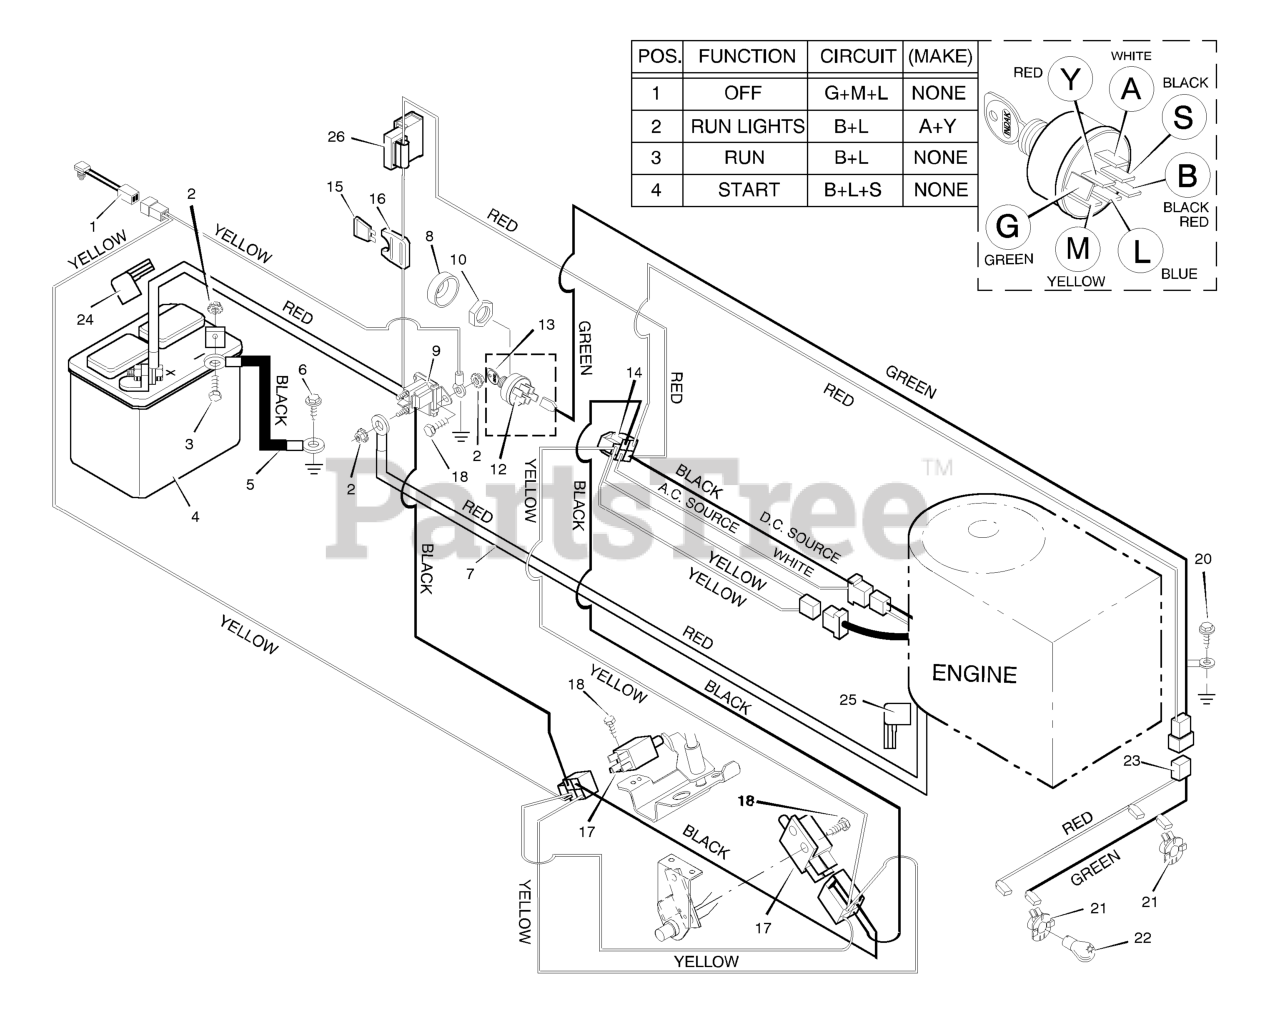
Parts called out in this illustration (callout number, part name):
1	Switch, Seat Sensor
2	Locknut
3	Bolt, Hex
4	Battery
5	Cable, Battery Ground
7	Cable, Red Battery
8	Cap, Ignition
9	Solenoid
10	Nut
12	Switch, Ignition
13	Key, Ignition
14	Harness, Chassis Wire
16	Holder, Fuse
17	Switch, Clutch
20	Screw
21	Socket, Light
22	Bulb, Light
23	Harness, Light Wire
24	Cover, Terminal
25	Cover,
26	Ammeter
